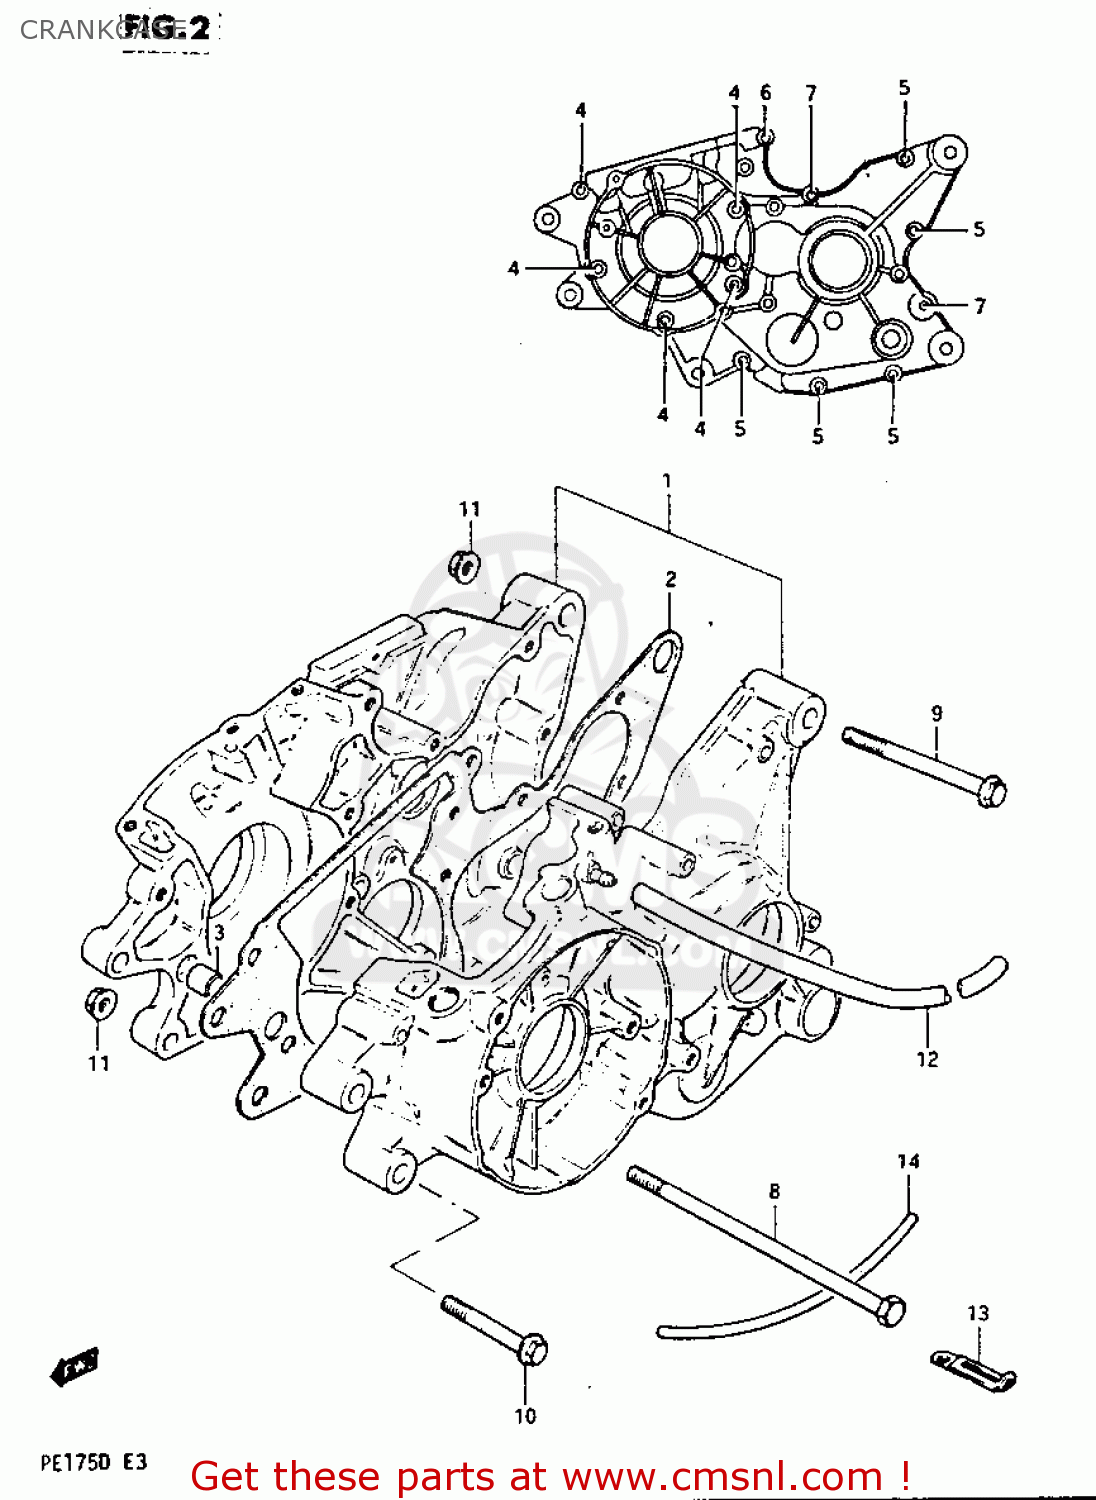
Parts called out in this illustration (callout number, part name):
1	CRANKCASE SET
2	GASKET,CRANKCASE
3	PIN
4	SCREW
5	SCREW
6	SCREW
7	SCREW 6X60
8	BOLT 8X175
9	BOLT (8X95)
10	BOLT 8X65
11	NUT
12	HOSE,FUEL
13	CLAMP
14	HOSE(4X7X600)
